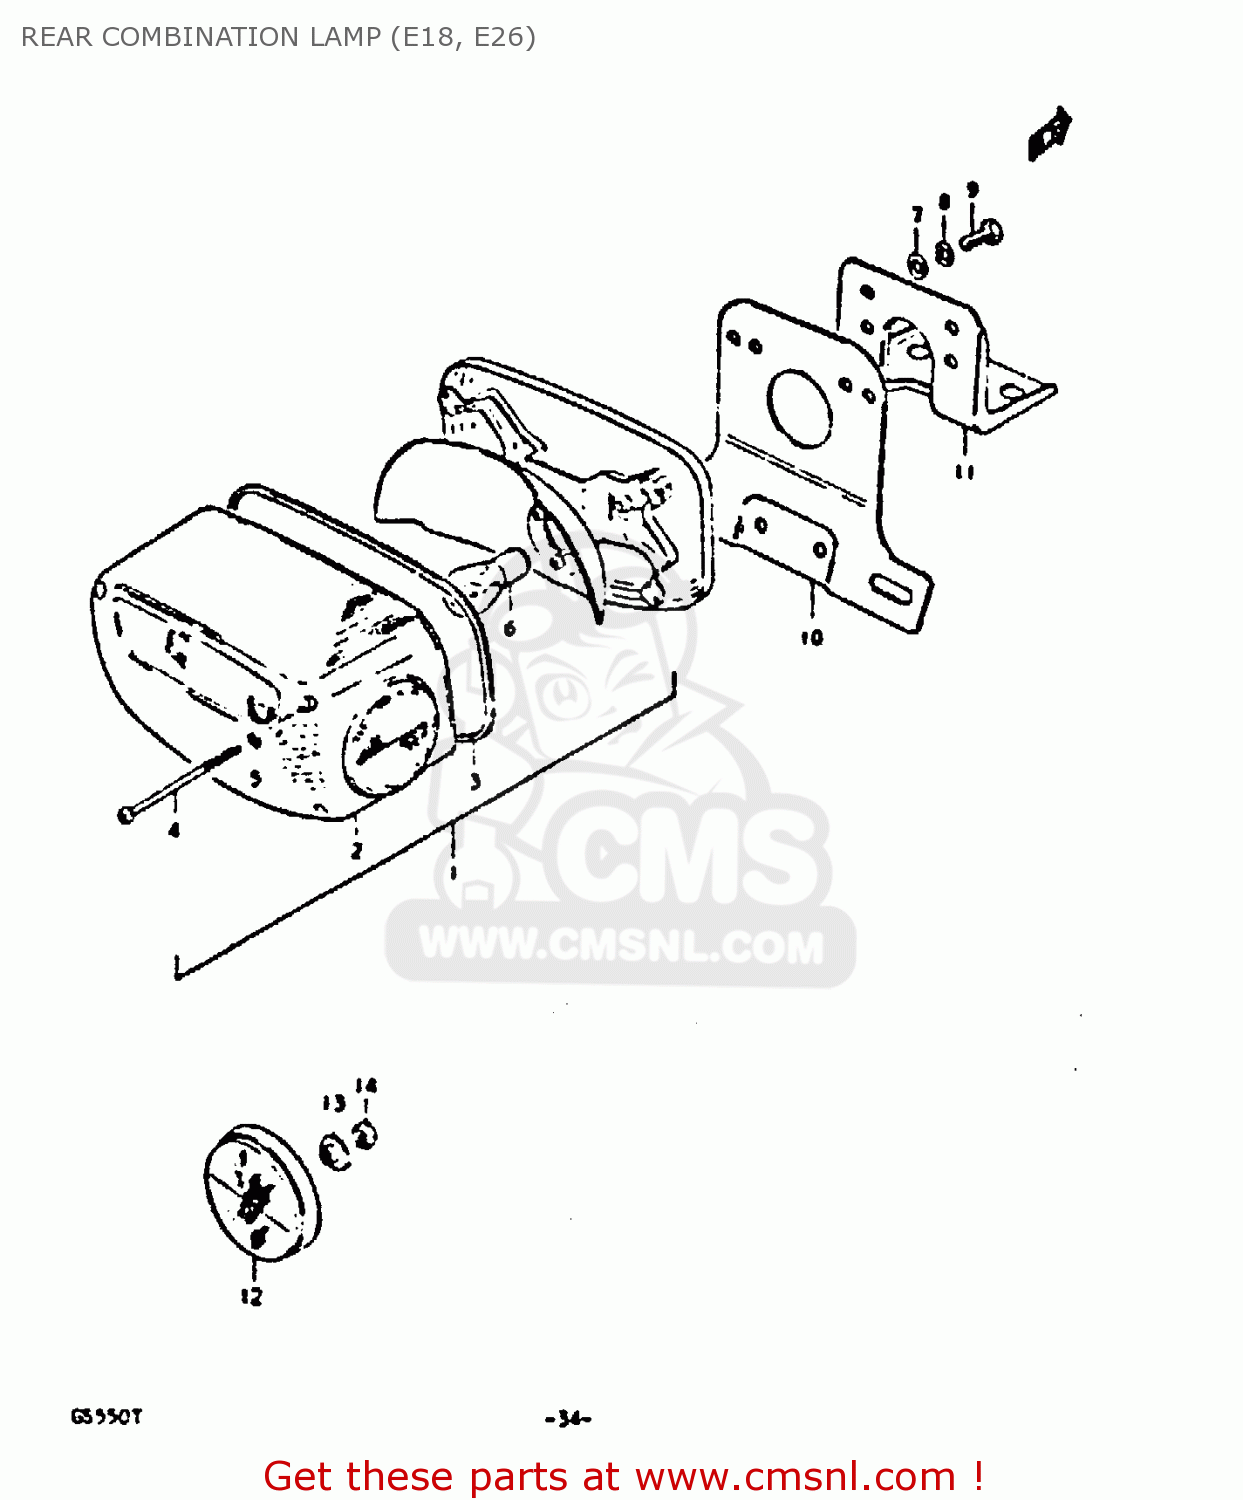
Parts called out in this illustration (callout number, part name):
1	LAMP ASSY, REAR COMBINATION
2	LENS
3	GASKET (NAS)
4	SCREW
5	GASKET (NAS)
6	BULB(12V21/5W)
7	WASHER
8	LOCK WASHER
9	BOLT
10	PLATE, LICENCE
11	BRACKET,LICENSE PLATE
12	REFLECTOR,REFLEX
13	SPACER
14	NUT
